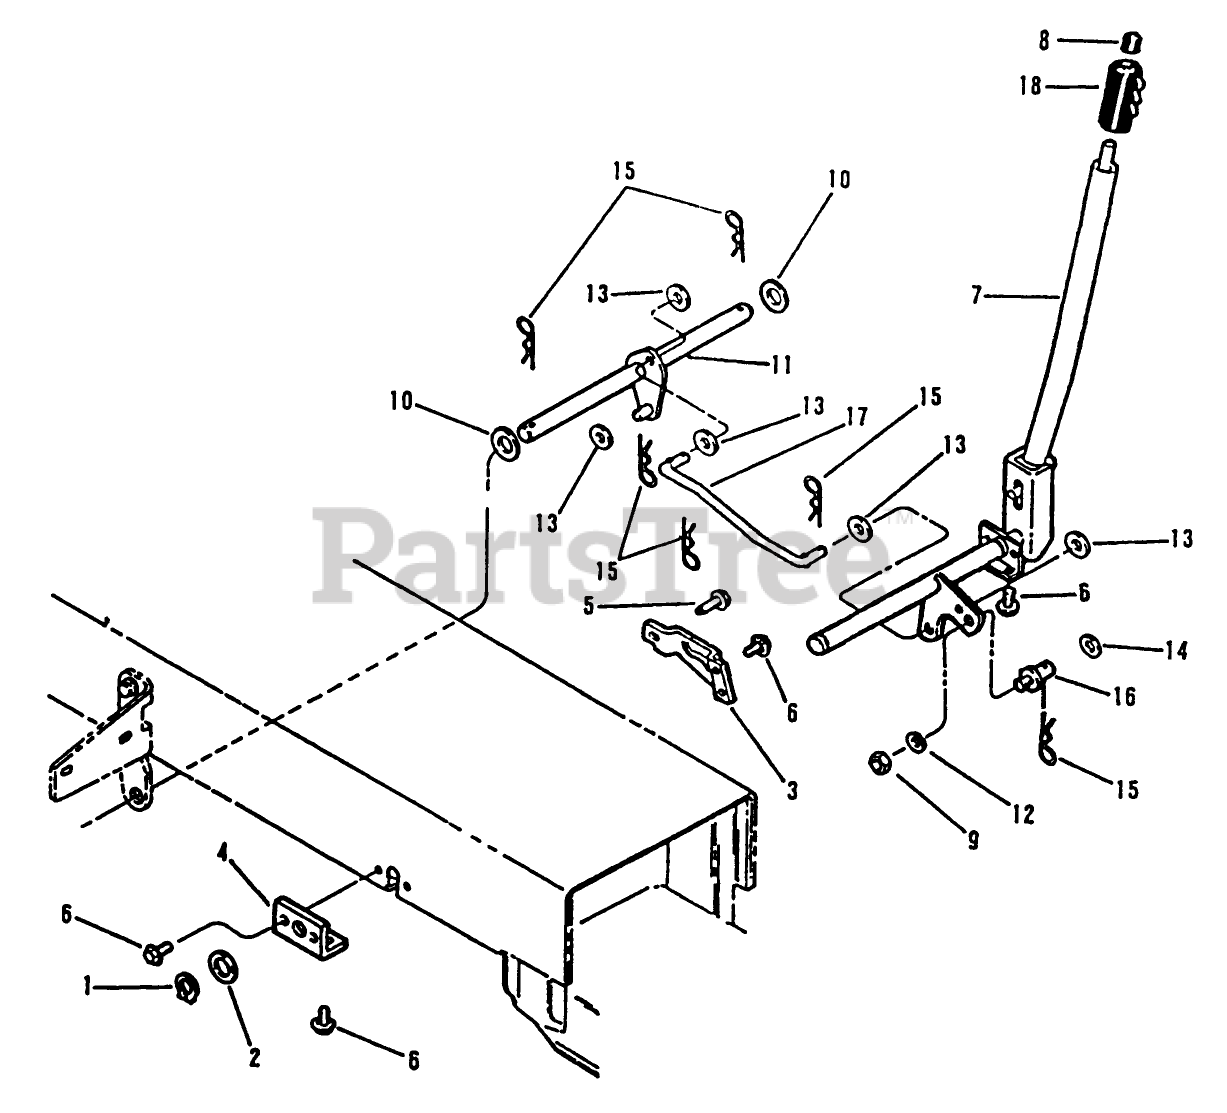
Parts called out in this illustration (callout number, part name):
1	RING-RETAINING
2	WASHER
5	SCREW
8	TIP-ROD
9	NUT
12	WASHER
13	WASHER
15	PIN-HAIR
